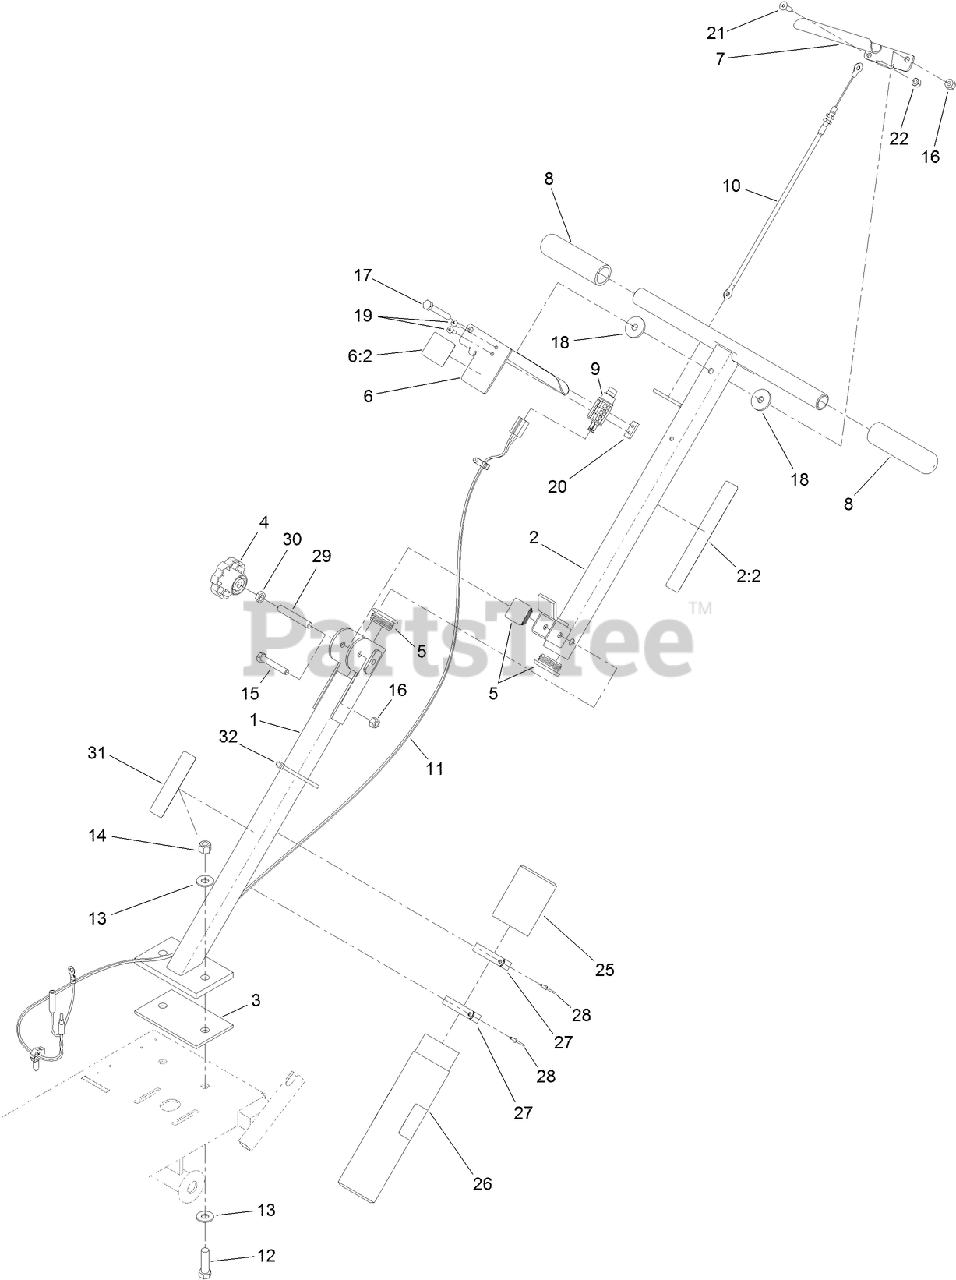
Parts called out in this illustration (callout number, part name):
1	HANDLE-LOWER
2	HANDLE ASM
2:2	DECAL-CAUTION
3	GASKET-HANDLE
5	PLUG-TUBE
6	PLUNGER HANDLE ASM
6:2	DECAL-ENGAGE
7	HANDLE-THROTTLE
8	GRIP-HANDLE
9	SWITCH-PLUNGER, NC (W/COVER)
10	CABLE-THROTTLE
11	HARNESS-WIRE
12	SCREW-HH
13	WASHER-FLAT
14	NUT-LOCK, NI
15	SCREW-HH
16	NUT-LOCK, NI
17	SCREW-HH
18	WASHER
20	PLATE-TAPPED
21	SCREW-TORX
22	NUT-LOCK, NI
25	CAP-HOUSING
26	TUBE-MANUAL
27	CLAMP-R
28	RIVET-POP
29	SCREW-HSH
30	NUT-JAM
31	DECAL-ARRESTER, SPARK
32	TIE-CABLE
